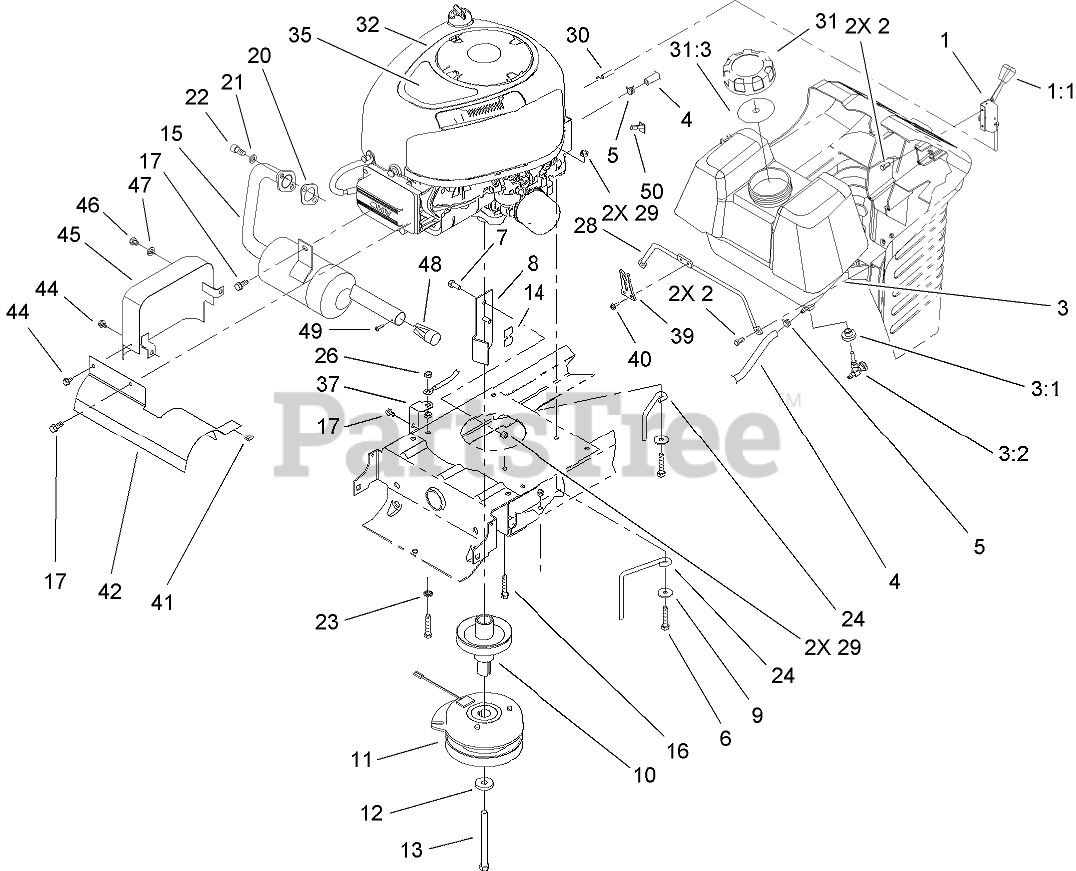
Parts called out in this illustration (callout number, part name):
1	THROTTLE CONTROL ASM
2	SCREW-SPECIAL
3	GAS TANK ASM
3:1	BUSHING
3:2	VALVE-FUEL
4	HOSE-FUEL
5	CLAMP-HOSE
6	SCREW-HH
7	SCREW-HH
8	STOP-CLUTCH
9	WASHER-PIVOT
10	PULLEY-ENGINE
11	CLUTCH-PTO, ELECTRIC
12	WASHER
13	SCREW-HH
14	BUMPER
15	MUFFLER
16	SCREW-HWH, TAPTITE
17	SCREW-HWH
20	GASKET-EXHAUST
21	WASHER-LOCK
22	SCREW-HSH
23	WASHER-LOCK
24	GUIDE-BELT, RH
26	NUT-KEPS
28	ROD-TANK, GAS
29	NUT-LOCK, NI
30	THROTTLE CABLE ASM
31	GAS CAP ASM
31:3	GASKET-CAP, GAS
35	DECAL-ENGINE
37	BRACKET-GROUND
39	LATCH-HOOD
40	SCREW-HWH
41	CLIP-TINNERMAN
42	SHIELD-MUFFLER
44	SCREW-HWHTF
45	HEAT SHIELD ASM
46	SCREW-HH
47	WASHER-LOCK
48	SCREEN-SILENCER, EXHAUST
49	SCREW-THD FORM, HWH
50	REDUCER-THROTTLE, RPM
